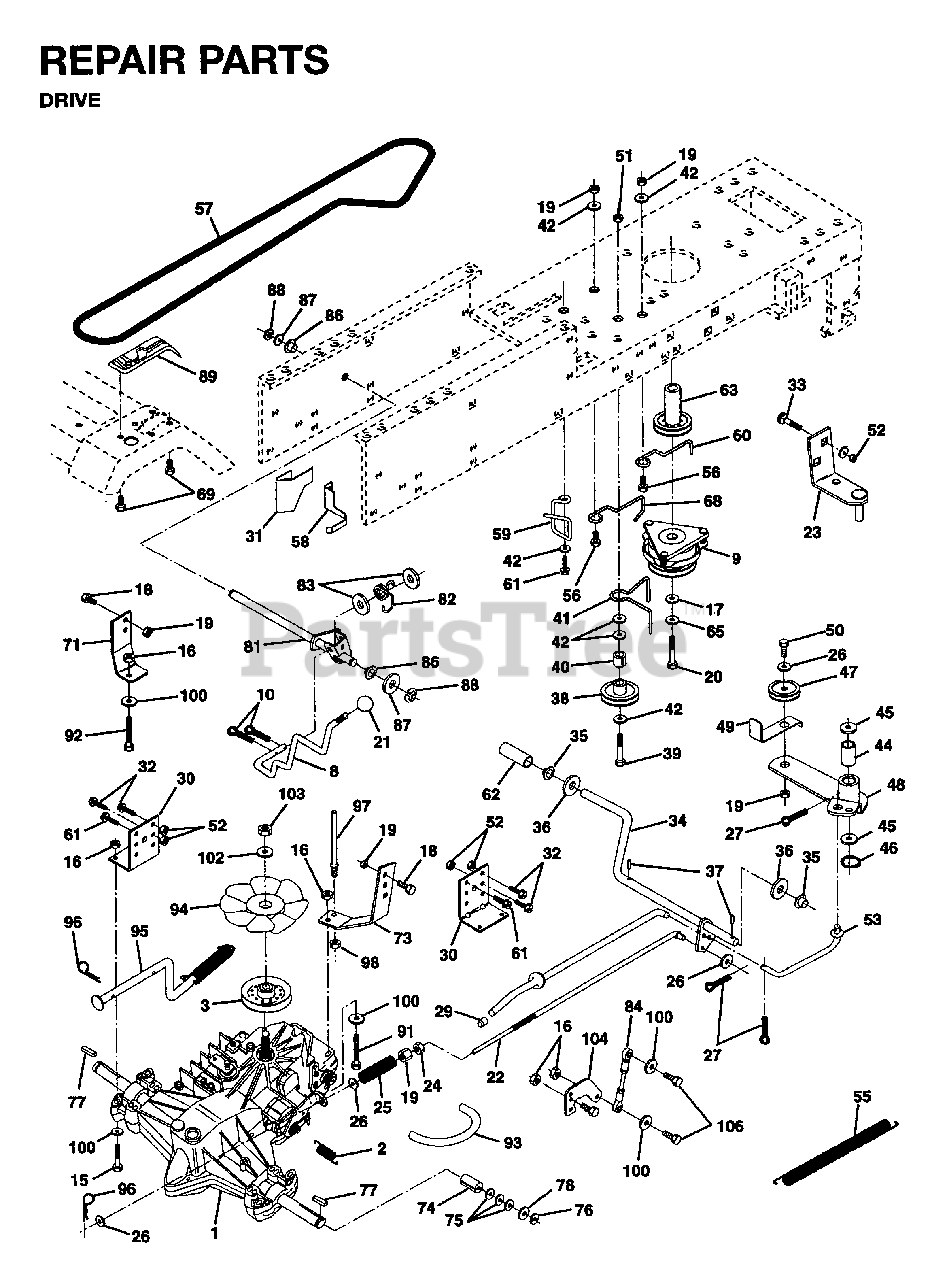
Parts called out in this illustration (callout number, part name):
1	TRANSAXLE ASMBLY
2	SPRING BRAKE
3	PULLEY, TRANSAXLE
8	SHIFT ROD
9	CLUTCH ELECT 1051B
10	PIN COTTER
15	BOLT HEX**
16	NUT.71038.31-18.HEX.NYLOCK
19	LOCKNUT
20	BOLT
21	KNOB.DELUXE.(PISTOL.GRIP).BLAC
22	ROD BRAKE HYDRO
23	BRACKET ASM MTG
24	NUT.HEX.3/8-16UNC
25	SPRING ROD LT
26	WASHER
27	COTTER PIN
29	PLUNGER CAP
30	BRACKET TRANSAXLE
31	KEEPER BELT LH
32	BOLT
33	BOLT
34	SHAFT FOOT PEDAL
35	BEARING.NYLON
37	DRIVE PIN
38	PULLEY.IDLER.FLAT
40	SPACER T
41	BELT KEEPER LT
42	WASHER
44	BEARING LT
45	WASHER LT
46	KLIP RING
47	IDLER PULLEY
48	ARM IDLER
49	RETAIN BELT
50	BOLT
51	LOCKNUT
52	LOCKNUT
53	LINK, CLUTCH LT
55	SPRING, RETURN LT
57	DRIVE BELT, LTH & YTH TRACTORS
58	KEEPER BELT LH
59	KEEPER CENTER SPAN
60	KEEPER BELT ENGLH
62	PEDAL COVER T
63	PULLEY CLU ELEC
65	LOCKWASHER
68	KEEPER,BLT ENG LT
69	SCREW.HI-LO.CONSOLE
71	STRAP LH TORQUE
73	STRAP RH TORQUE
74	SPACER SPLIT
76	E-RING LT
77	SQUARE KEY
81	SHAFT ASSY
82	SPRING,TORSION
86	BUSHING.STEERING.ROD
88	KLIP RING
89	CONSOLE HYDRO LT
92	HEX BOLT
93	FUEL LINE
94	FAN 7" HYDRO
95	CONTROL ARM, BYPASS HYDRO
96	RETAINER M
97	KEEPER BELT RH
98	NUT.HEX.3/8-16UNC
100	WASHER - 15X7.3X1.6
104	CONTROL ARM
106	BOLT.5/16-18X1-1/4 FULL.THREAD
